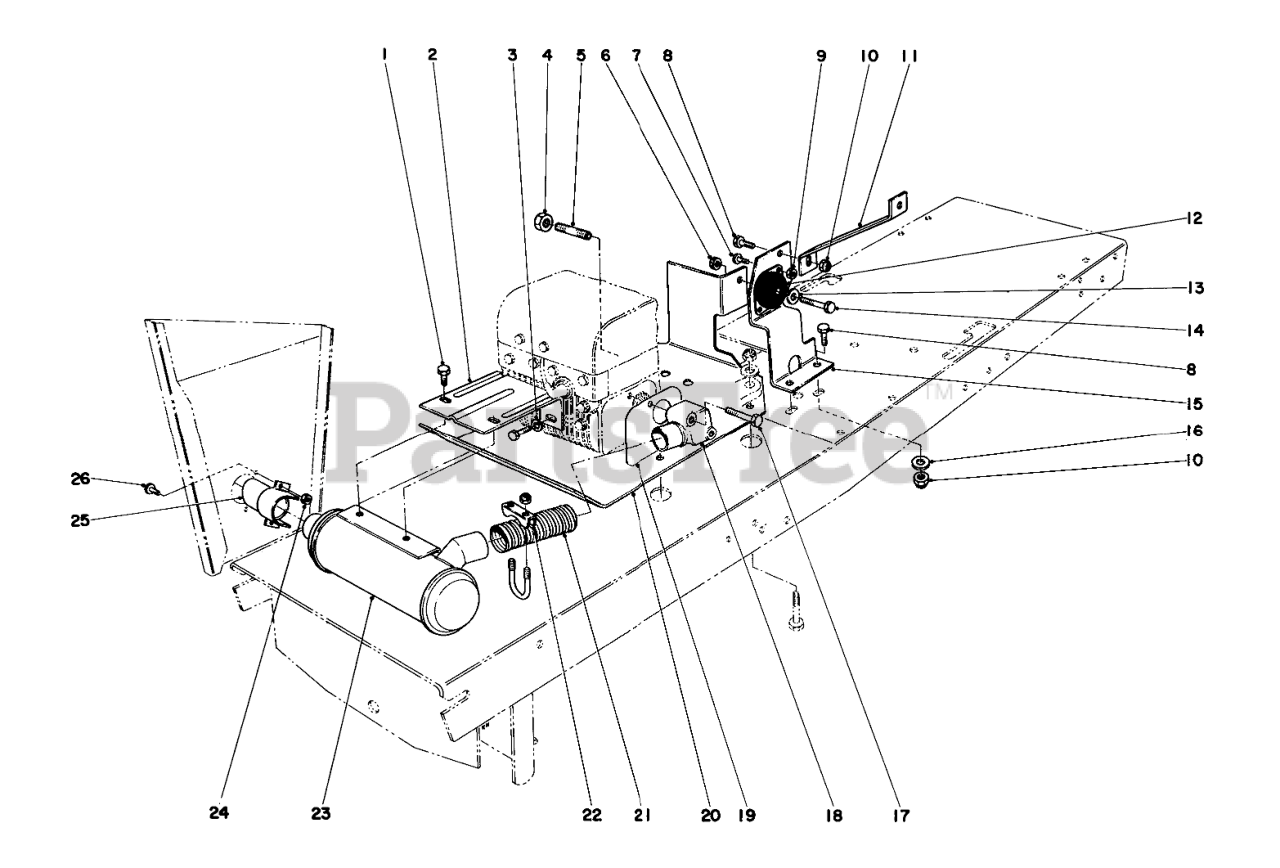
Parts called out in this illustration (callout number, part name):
1	SCREW-HH
2	Hanger Muffler
3	WASHER-LOCK
4	Cap-Pipe
5	NIPPLE 3/8NPTX 1.50
6	NUT-LOCK, SIDE
7	SCREW-PTH
8	SCREW-HH
9	NUT-LOCK, SIDE
10	NUT-LOCK, CONE
11	Brace
12	Mount Rubber
13	WASHER-FLAT
14	SCREW-HH
15	Mount Rear
16	WASHER-FLAT
17	Capscrew
18	Elbow Exhaust
19	Heat Shield
20	Engine Mount
21	Exhaust Tubing
22	Muffler Clamp
23	Muffler
24	NUT-LOCK, SIDE
25	Exhaust Tip
26	SCREW-PPH
